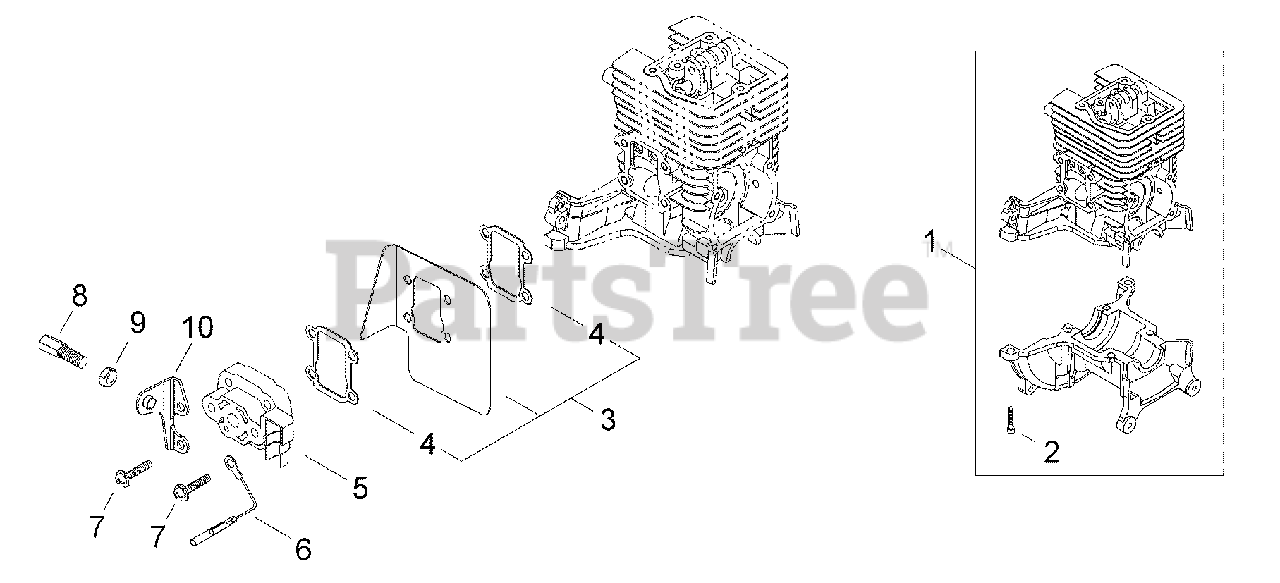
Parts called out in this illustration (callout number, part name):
1	CYLINDER & CRANKCASE ASSY
2	BOLT 5×16
3	SHIELD ASSY, INTAKE HEAT
4	GASKET, EXHAUST
5	INSULATOR WITH REED VALVE
6	LEAD - GROUND L= 110 MM
7	SCREW M5×22
8	ADJUSTER, THROTTLE CABLE
9	NUT, ADJUSTER LOCK M6
10	BRACKET, THROTTLE CABLE
